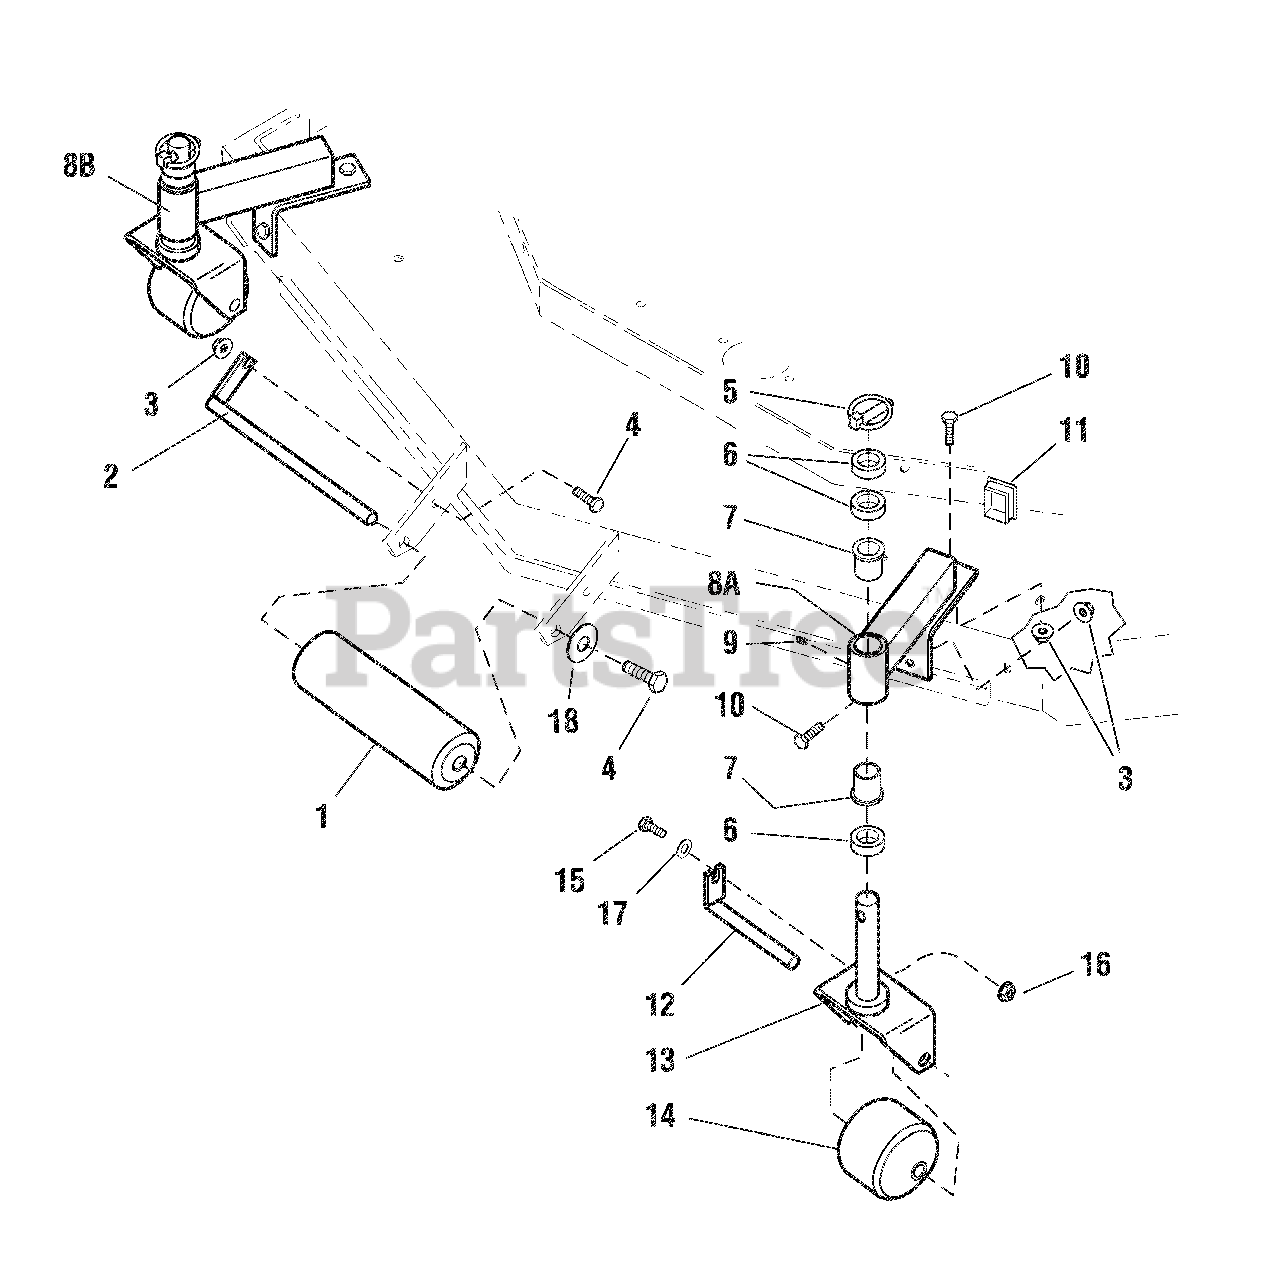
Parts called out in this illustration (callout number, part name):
1	ROLLER, DECK
3	NUT, 3/8-16 Hex Large Serrated Flange
4	BOLT, 3/8-16 X 1" GD5 CZ
5	PIN, LYNCH, 7/16"
6	SPACER, 1.02 x 1.56 x .50
7	BUSHING, FLANGE
8A	ASSM, ARM, DECK CASTER, LH
8B	ASSM, ARM, DECK CASTER, RH
9	GREASE FITTING, 1/4-28 Straight
10	BOLT, 3/8-16 X 3/4" GD5 CZ
11	CAP, 1-1/2" X 2" X 11GA, PLASTIC
12	WELD, CASTER ROLLER PIN - RED
13	WELD, CASTER YOKE - RED
14	ROLLER, Caster
15	BOLT, 5/16-18 X 3/4 GD5
16	NUT, 5/16-18 HEX SERRATED FLANGE (SMALL)
17	WASHER, 5/16 GRADE 9, FLAT
18	WASHER, .390 X 1.50 X .109, YZ
